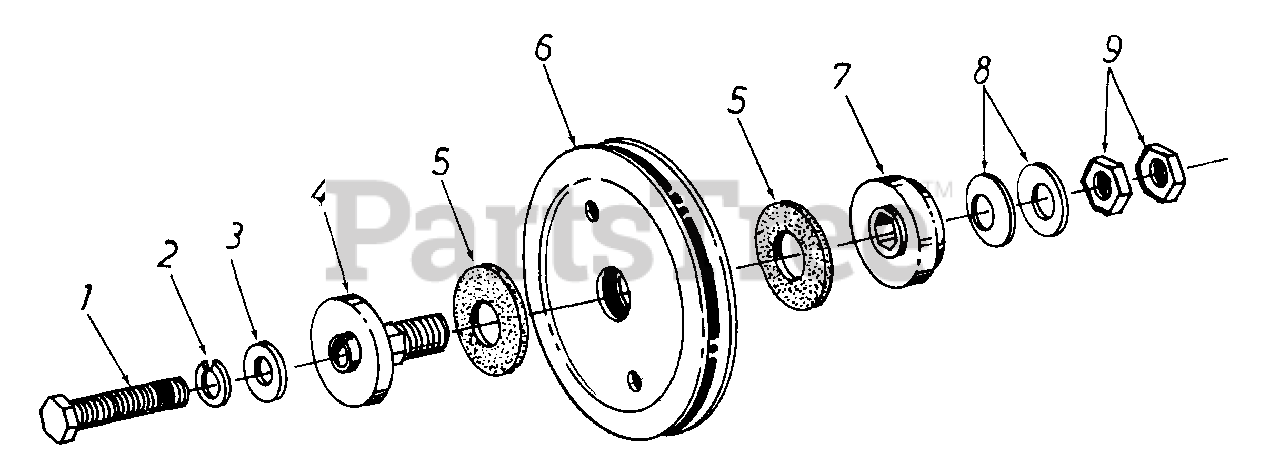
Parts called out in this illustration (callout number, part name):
1	Hex Bolt 5/16-24 x 1.50" Lg. w/lock
2	L.-Wash. 5/16" I.D.
3	Fl.-Wash. 5/16" I.D. x 1-1/8" O.D. x .120
4	Friction Disc Ass'y.
5	Friction Pad
6	Input Pulley
7	Floating Disc
8	Spring Bell. - Wash.
9	Hex Nut 1.0-14 Jam
